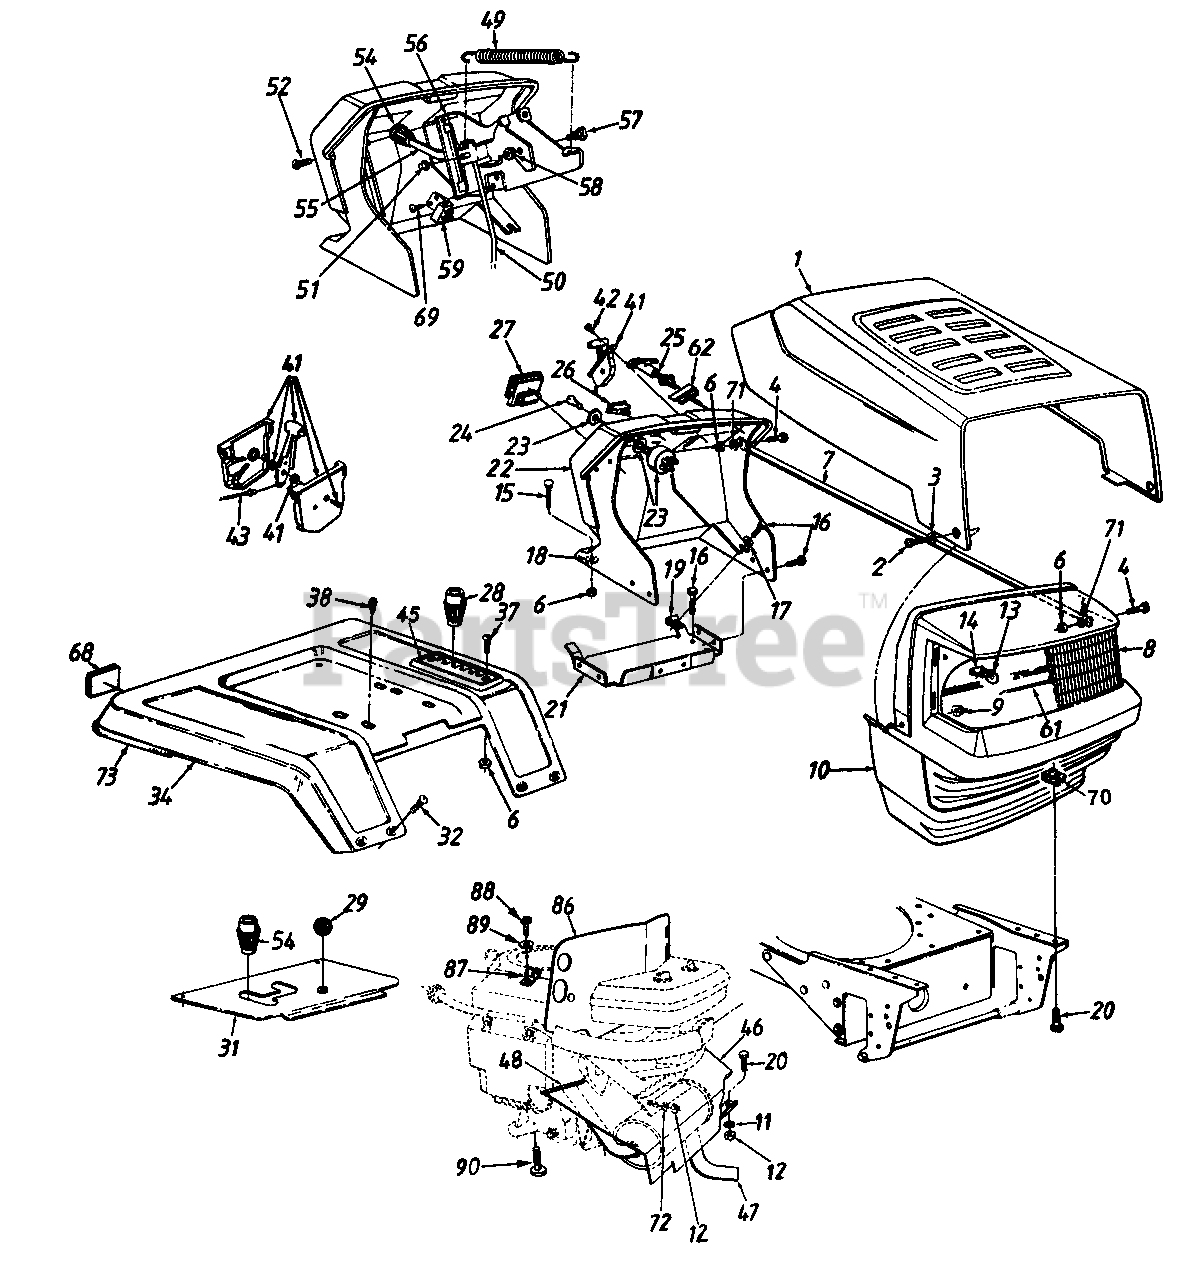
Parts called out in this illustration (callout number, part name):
3	Spr. Wash. .265" I.D. x .562" O.D.
4	Hex Bolt 1/4-20 x .62" Lg.
6	Hex Sems Nut 1/4-20 Thd.
9	Flange L-Nut 1/4-20 Thd.
10	Grille
11	L-Wash. 5/16" I.D.
12	Hex Nut 5/16-18 Thd.
13	Lamp
14	Socket
15	Carriage Bolt 1/4-20 x 1.0" Lg.
16	Hex AB-Tap Scr. 1/4 x .62" Lg.
17	Fl-Wash. .281" I.D. x .73" O.D.
18	Bolt Retainer 1/4" I.D.
19	Speed Nut 1/4-20 Thd.
20	Hex Bolt 5/16-18 x .75" Lg.
23	Ignition Switch
24	Ignition Key
25	Choke Control
26	Light Switch
27	Ammeter
28	Shift Knob
32	Carriage Bolt 1/4-20 x .5" Lg.
38	Hex Wash. Hd AB-Tap Scr 5/16 x .75" Lg
41	Throttle Box Ass'y.
42	Truss Mach AB-Tap Scr #10 x .5" Lg
43	Throttle Control Wire 35" Lg.
45	6-Speed Selector Plate
46	Front Heat Shield
47	Muffler
48	Trim Strip 12" Lg.
49	Ext. Spring 5.06" Lg.
50	Deck Control Rod
51	Speed Nut 1/4" Rod
52	Torx Mach Scr. 1/4 x .62" Lg
54	PTO Knob
55	PTO Lever
56	PTO Bracket
57	Shld. Bolt 437" Dia. x .162"
58	Hex L-Nut 5/16-18 Thd
59	Safety Switch (PTO)
61	Grille Reflector Label
62	Retainer Clip
68	Reflector
69	Hex Wash Hd. B-Tap Scr. #10 x 38" Lg.
70	U-Nut 5/16-18 Thd.
71	Fl-Wash. .28" I.D. x .75" O.D
72	Spec. L-Wash. 5/16" I.D
73	Trim Strip 81" Lg.
86	Top Heat Shield
87	Clamp
88	Truss Mach Scr. #10 x .5" Lg.
89	Fl-Wash. .188" I.D. x .43" O.D.
90	Hex L-Wash TT-Tap Scr. 3/8-16 Thd.
